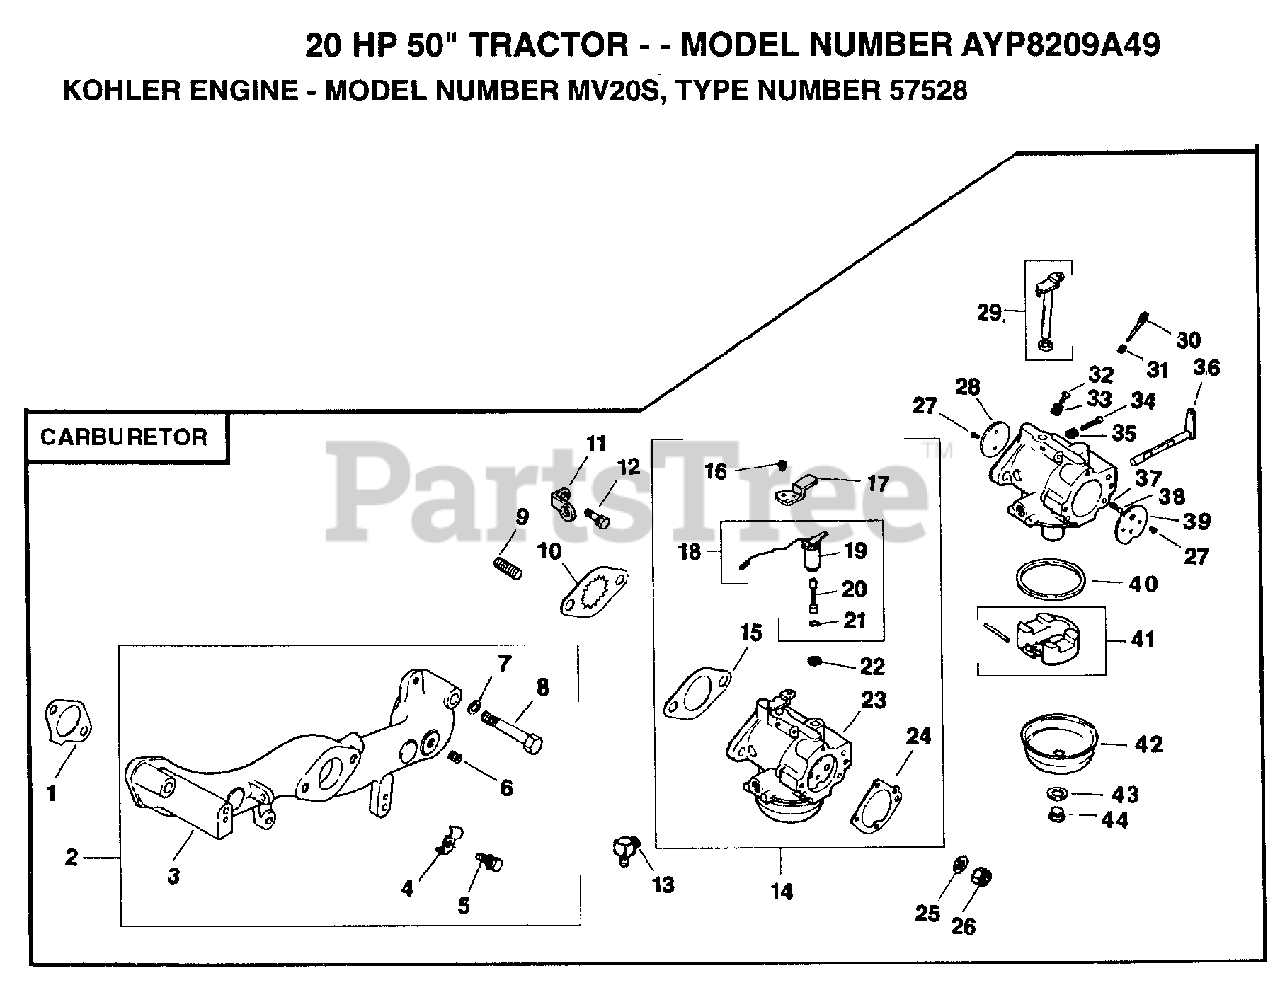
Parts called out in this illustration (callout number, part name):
4	CLAMP
5	SCREW
6	PLUG
7	WASHER
8	SCREW, 5/16-18X1-1/4 (4)
11	STRAP
12	SCREW
14	KIT, CARB. W/GASKET
15	GASKET
16	SCREW, SLT. #6-40X1/4
17	BRAKET, SOLENOID
18	KIT, SOLENOID
20	ROD, SOLENOID
22	GASKET, NEEDLE SEAT
24	GASKET, AIR CLEANER
25	WASHER, INTERNAL TOOTH
26	NUT
29	SHAFT, THTLE,W/LEVER & SEAL
44	SCREW, BOWL RETAINER
